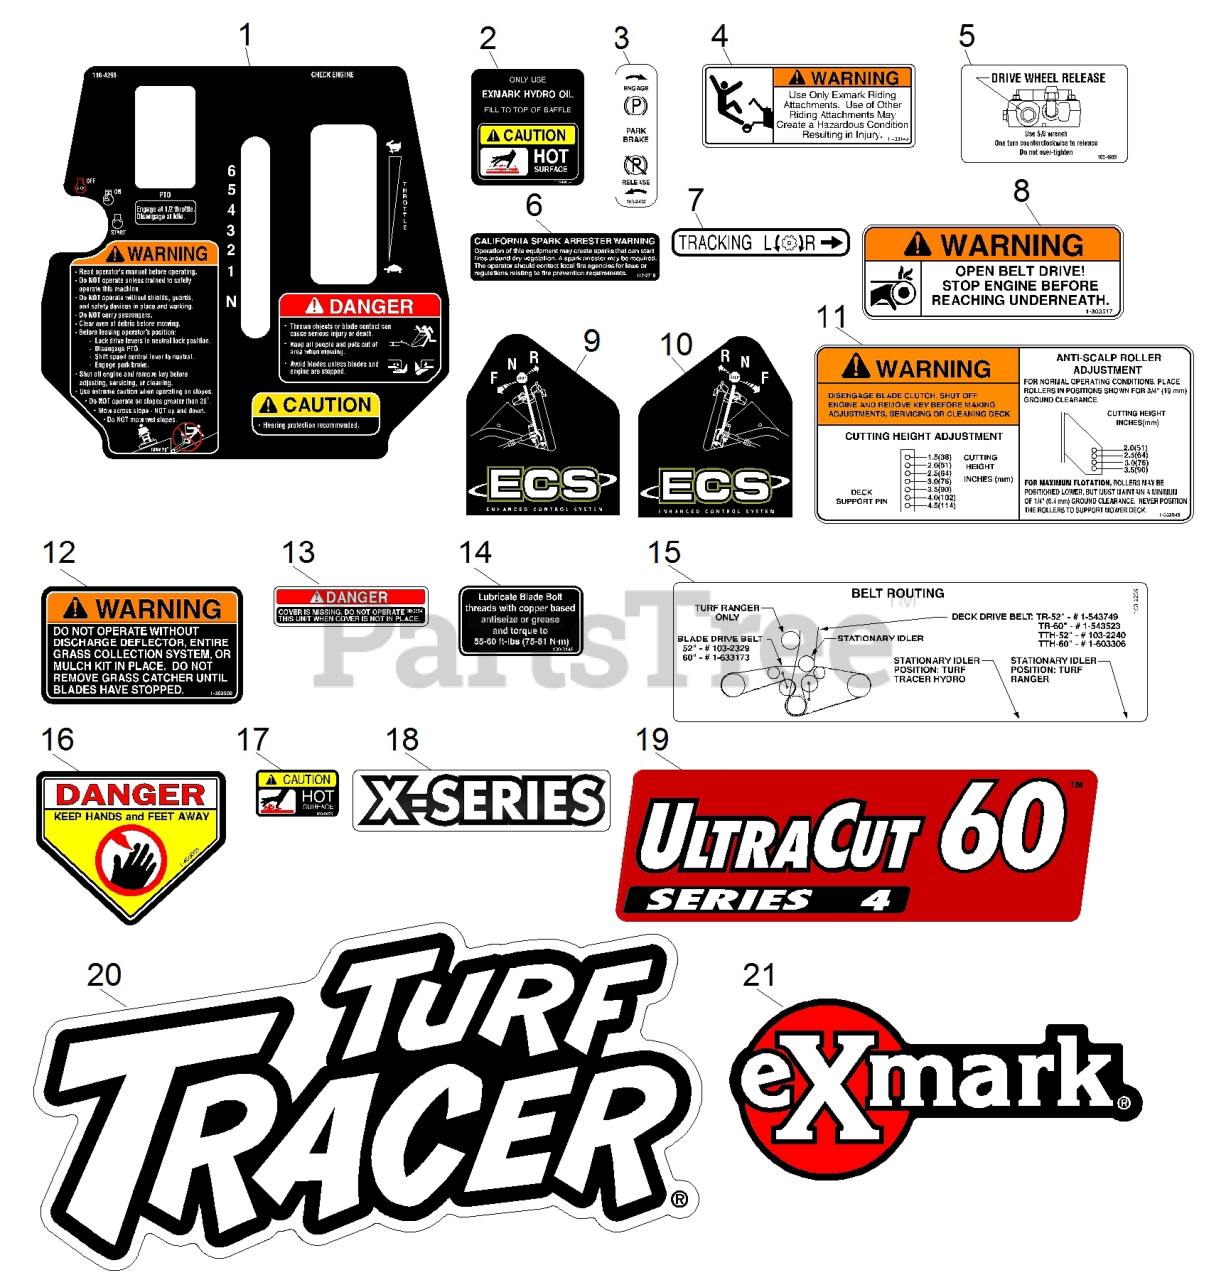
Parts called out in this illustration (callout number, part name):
1	DECAL,CONSOLE TTX
2	DECAL-HYDRAULIC TANK
3	DECAL,PARKING BRAKE
4	DECAL,SULKY WARNING
5	DECAL,DRIVE RELEASE
6	DECAL-ARRESTER, SPARK
7	DECAL,TRACKING ADJUST
8	DECAL,BELT DRIVE
9	DECAL,LH ECS INSTRUCTION
10	DECAL,RH ECS INSTRUCTION
11	DECAL,ANTI SCALP
12	DECAL-WARNING, DISCHARGE
13	DECAL-COVER, MISSING
14	DECAL,BOLT TORQUE
15	DECAL,BELT ROUTING
16	DECAL-DANGER
17	DECAL-CAUTION
18	DECAL-X-SERIES
19	DECAL,ULTRACUT 60 SERIES
20	DECAL,TTH MODEL
21	DECAL,EXMARK LOGO
